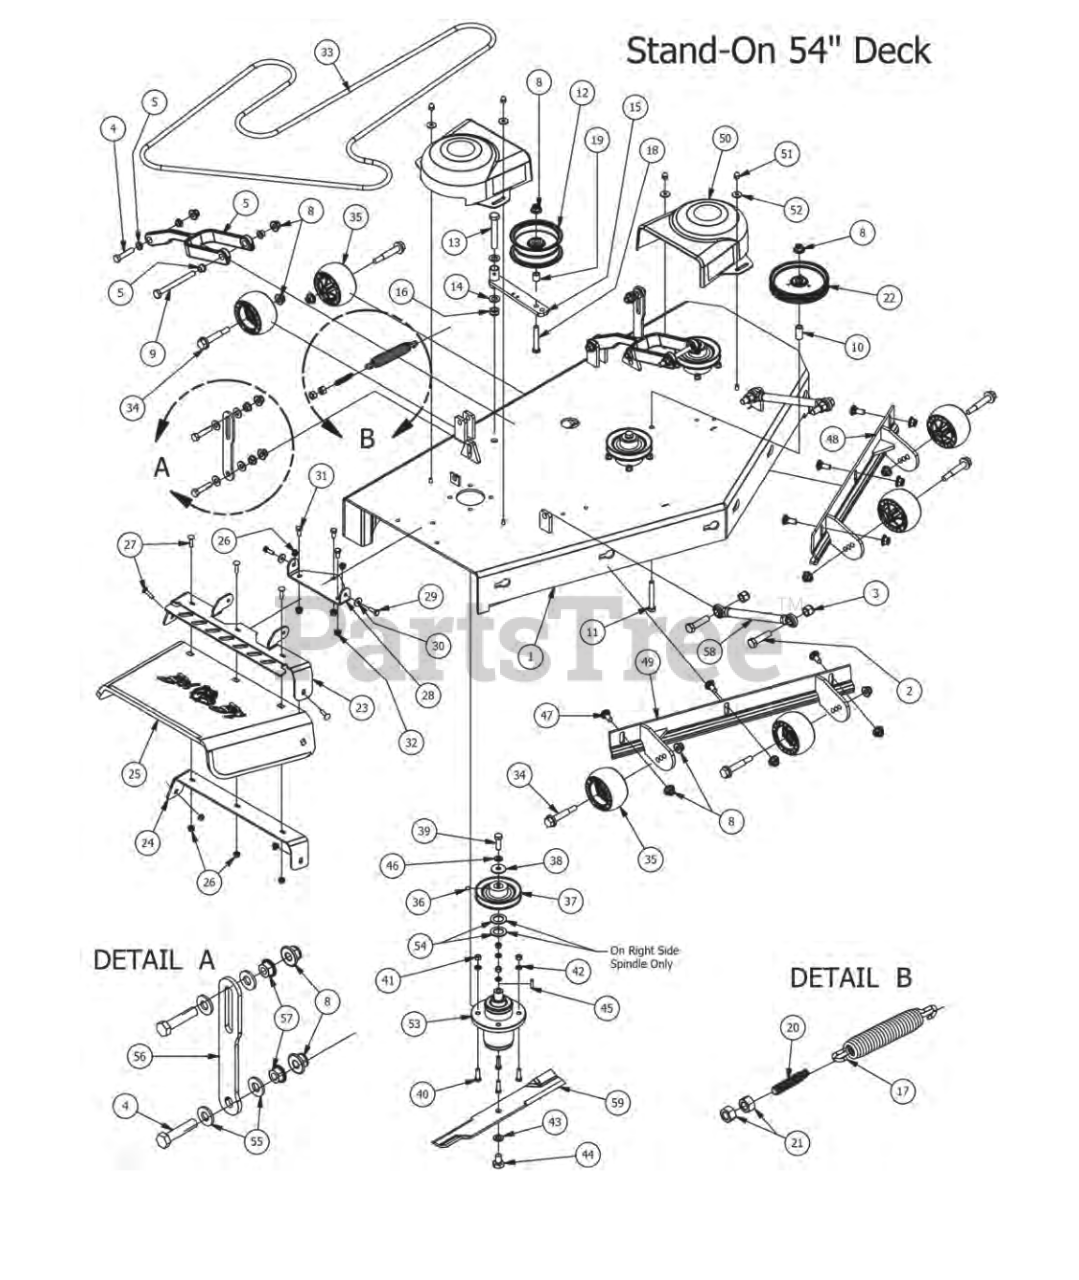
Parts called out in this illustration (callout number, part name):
1	54" 2015 Stand-On Deck (Welded Assembly)
2	5/8" x 2 1/2" Hex Bolt
3	5/8 Std NC Nylock Nut
4	1/2-13X 2-1/4 GR Hex Bolts
5	Deck Arm Assembly
8	1/2-13 Nylon Flange Nut-Orange
9	1/2" x 5 1/2" Bolt
10	.502 ID X.75 OD X 1.500 Leng
11	1/2 x 3 1/2 Flange Bolt Grade 8
12	5 3/4" Deck Idler Pulley
13	5/8" x 4" Hex Bolt
14	.635 ID Plastic Washer
15	Deck Idler 2009 AOS
16	5/8" Nylock (1/2 Jam)
17	2009 Deck/Pump Idler Spring
18	1/2-13 x GR 5 Hex Bolt Zinc
19	3/4 OD X 1/2 ID x 3\4 Length
20	All Thread-pump Idler Tensioner
21	1/2" Hex Nut
22	5-3/4 Idler Pulley
23	Upper Hanger
24	Discharge Lower Chute Bracket
25	Rubber Discharge Chute
26	5/16" Nylon Flange Nut
27	5/16" x 1 1/4" Carriage Bolt
28	Discharge Chute Hanger (deck mounted)
29	5/16" x 1" Bolt
30	360 ID Plastic Washer
31	3/8" x 3/4" Hex Bolt
32	3/8" Flange Nut
33	42" Deck Belt - B120
34	Deck Wheel Bolt
35	Anti-Scalp Rollers
36	5/16 Set Screw
37	5" Deck Pulley
38	1/2 Belleville Washer
39	1/2"-20 x 1 1/2 - Grade 5 Fine Thread Bolt
40	3/8" x 1 1/4" Hex Bolt
41	3/8-16 Hex Nuts Zinc
42	3/8" Lock Washer
43	5/8" Lock Washer
44	5/8" x 1 1/2" Gr8 Hex Bolt (Fine)
45	1/4" x 1" Key
46	1/2" Lock Washer
47	1/2" x 1 1/4 Carriage Bolt
48	54 Deck Adustable Front (Left)
49	54 Deck Adustable Front (Right)
50	Pulley Cover
51	Acorn nut-pulley Cover
52	.360 ID Plastic Washer-Black
53	OUTLAW SPINDLE ASSEMBLY
54	1 1/8" Flat Spacer
55	.505 Nylon Spacer
56	Longer deck hanger
57	1/2" Flange Nut
58	Turnbuckle (Top Link)
59	54" Deck Fusion Blade For Outlaw
